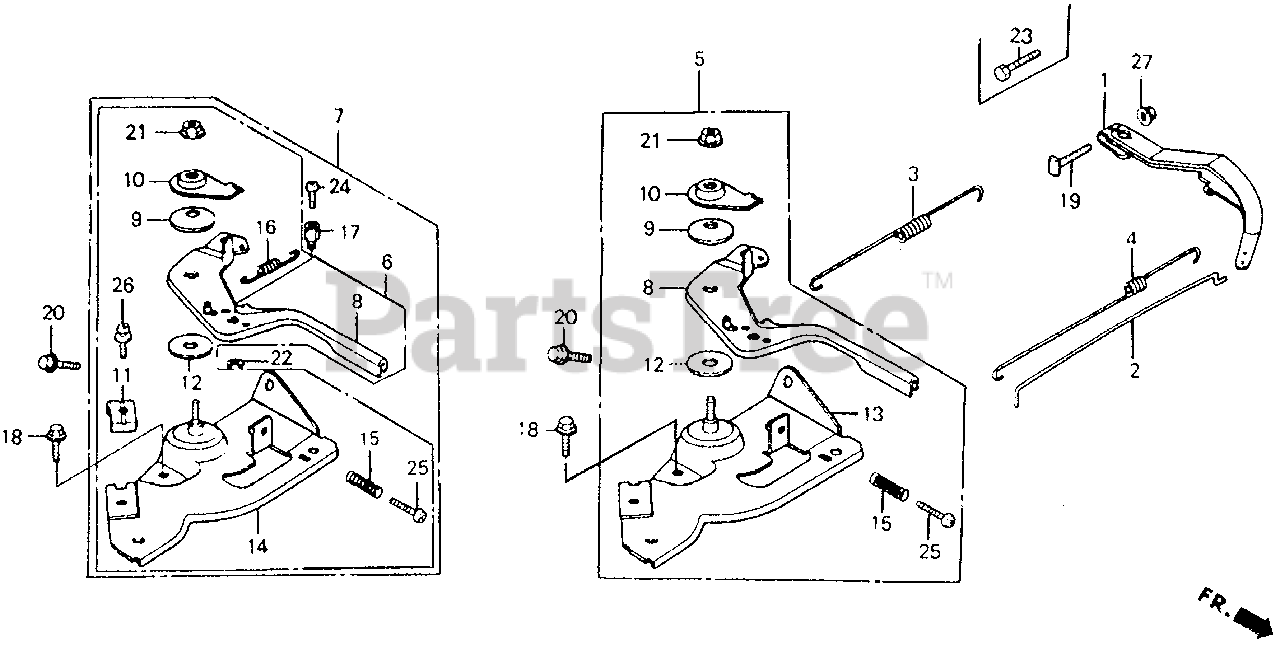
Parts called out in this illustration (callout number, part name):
1	ARM, GOVERNOR
2	ROD, GOVERNOR
3	SPRING, GOVERNOR
4	SPRING, THROTTLE RETURN
5	CONTROL ASSY.
8	LEVER, CONTROL
9	SPRING, LEVER
10	WASHER, CONTROL LEVER
12	SPACER, CONTROL LEVER
13	BASE, CONTROL
15	SPRING, CONTROL ADJUSTING
18	BOLT, FLANGE (6X12) (CT200)
19	BOLT, GOVERNOR ARM
20	BOLT, FLANGE (6X20) (CT200)
21	NUT, SELF-LOCK (6MM)
21	NUT, FLANGE (6MM)
23	BOLT, HEX. (6X20)
25	SCREW, PAN (5X20)
25	SCREW, PAN (5X25)
25	SCREW, PAN (5X28)
27	NUT, FLANGE (6MM)
